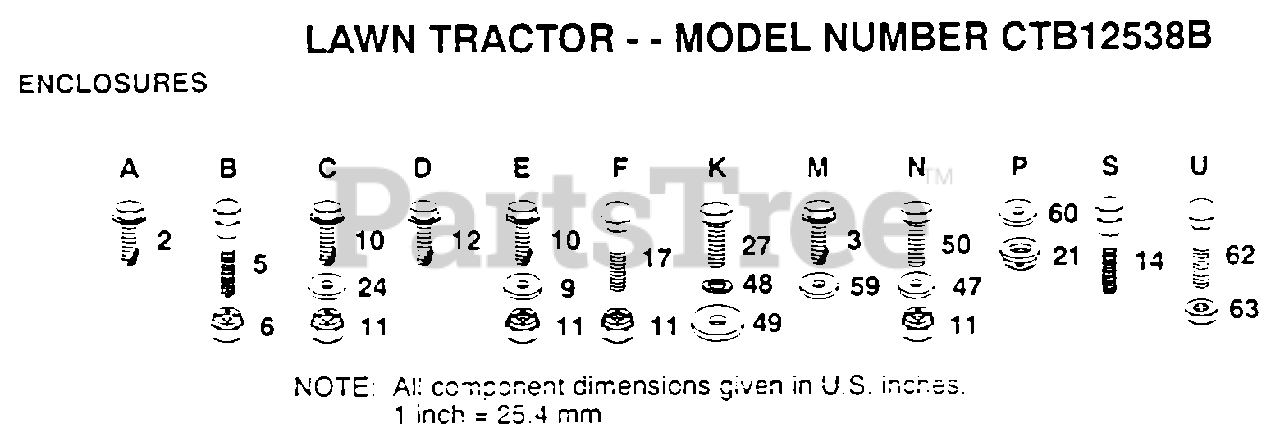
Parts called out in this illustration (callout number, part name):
2	SCREW
3	SCREW GTV
9	WASHER
12	SCREW LT
14	"BOLT,SHOULDER"
17	BOLT
21	PAL NUT LT
24	WASHER
27	BOLT
47	WASHER
48	LOCKWASHER
49	WASHER
50	BOLT
59	WASHER
60	WASHER PM
62	BOLT
